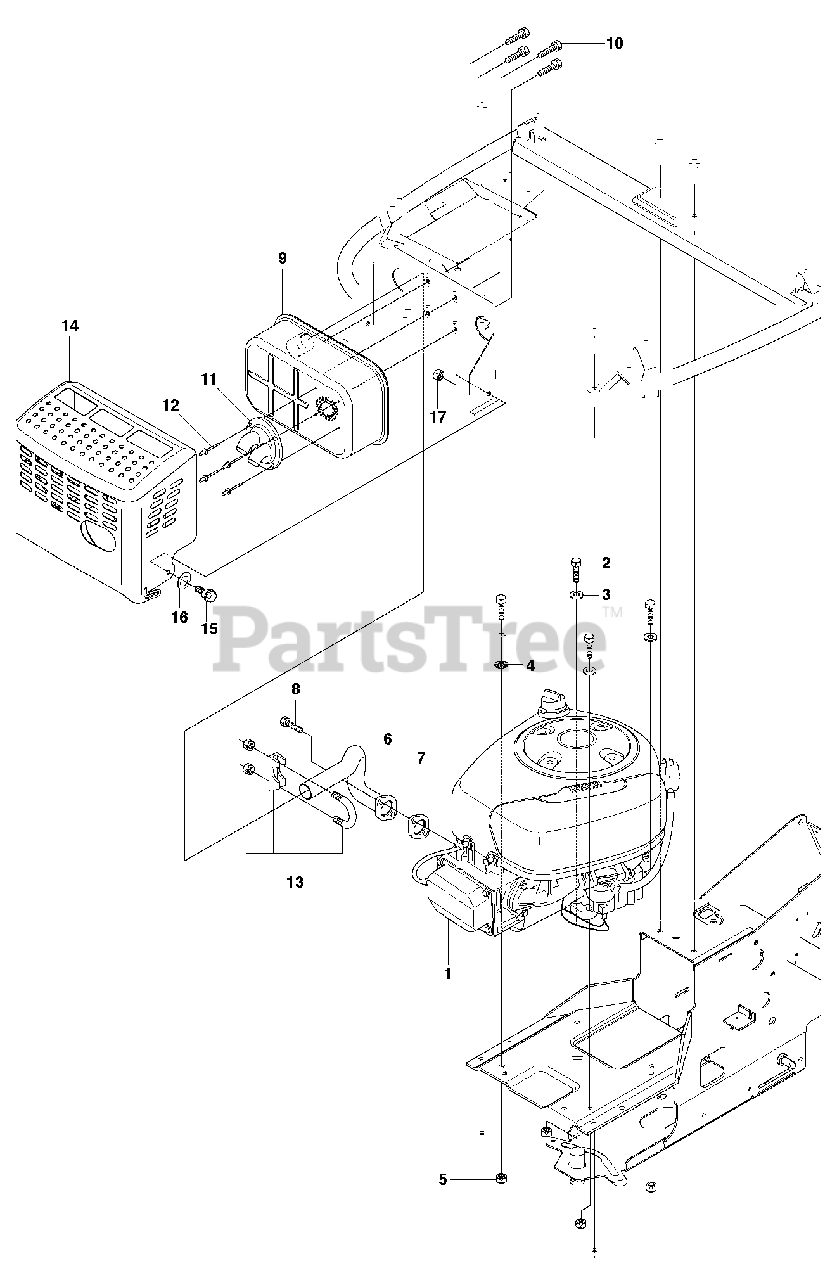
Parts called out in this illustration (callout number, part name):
3	WASHER BRB 8.4X17
5	LOCKNUT M8
9	MUFFLER
16	SPRINGWASHER
17	LOCKNUT M8
